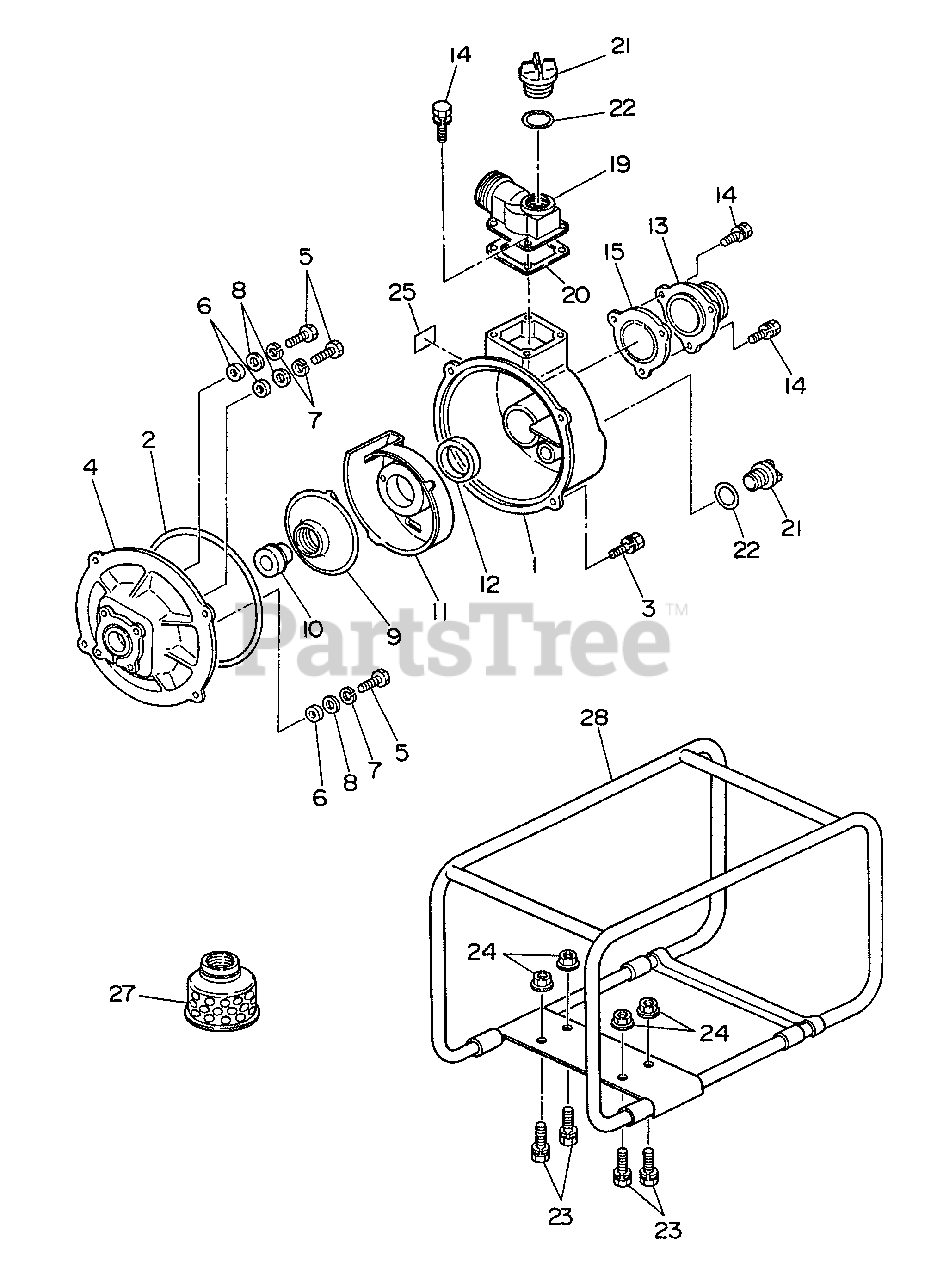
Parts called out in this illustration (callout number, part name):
2	GASKET
3	BOLT
4	COVER, PUMP CASE
7	LOCKWASHER
11	INNER CASING
13	SUCTION FLANGE (NPT)
14	BOLT
15	VALVE, CHECK
19	DELIVERY FLANGE (NPT)
21	PLUG
23	BOLT
24	NUT - FLANGE
25	LABEL, pump name
27	STRAINER, DEBRIS
28	FRAME
